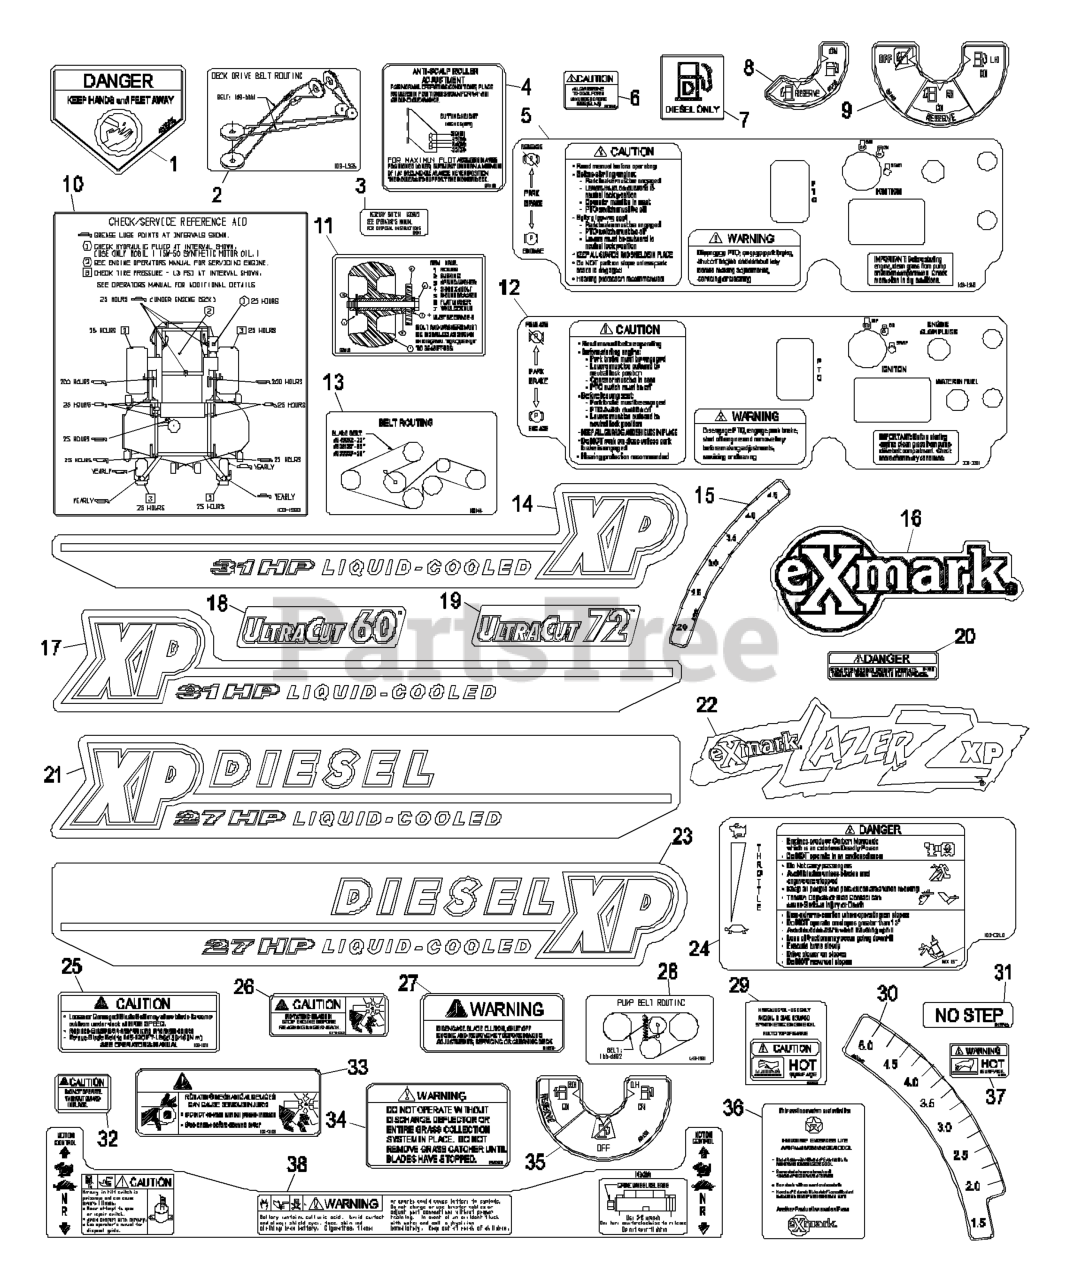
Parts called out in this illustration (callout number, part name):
1	DECAL-DANGER
2	DECAL,BELT ROUTING XP
3	DECAL-SWITCH, MERCURY
4	DECAL,ANTISCALP
5	Decal, Console 1
7	DECAL-FUEL
10	DECAL,CHECK/SERVICE XP *
11	DECAL,ROLLER MOUNTING
13	DECAL,BELT ROUTING
15	DECAL-HEIGHT, DECK
16	DECAL,EXMARK LOGO
18	DECAL,ULTRACUT 60
19	DECAL,ULTRACUT 72
20	DECAL-COVER, MISSING
25	DECAL,BOLT TORQUE
26	DECAL-FAN, RADIATOR
27	DECAL,WARNING
30	DECAL-HEIGHT, DECK
31	DECAL,NO STEP
32	DECAL-GUARD
34	DECAL-WARNING, DISCHARGE
35	DECAL, FUEL VALVE XPG
36	DECAL,SHELL COOLANT
37	DECAL-SURFACE, HOT
38	DECAL-CONSOLE, TOP
